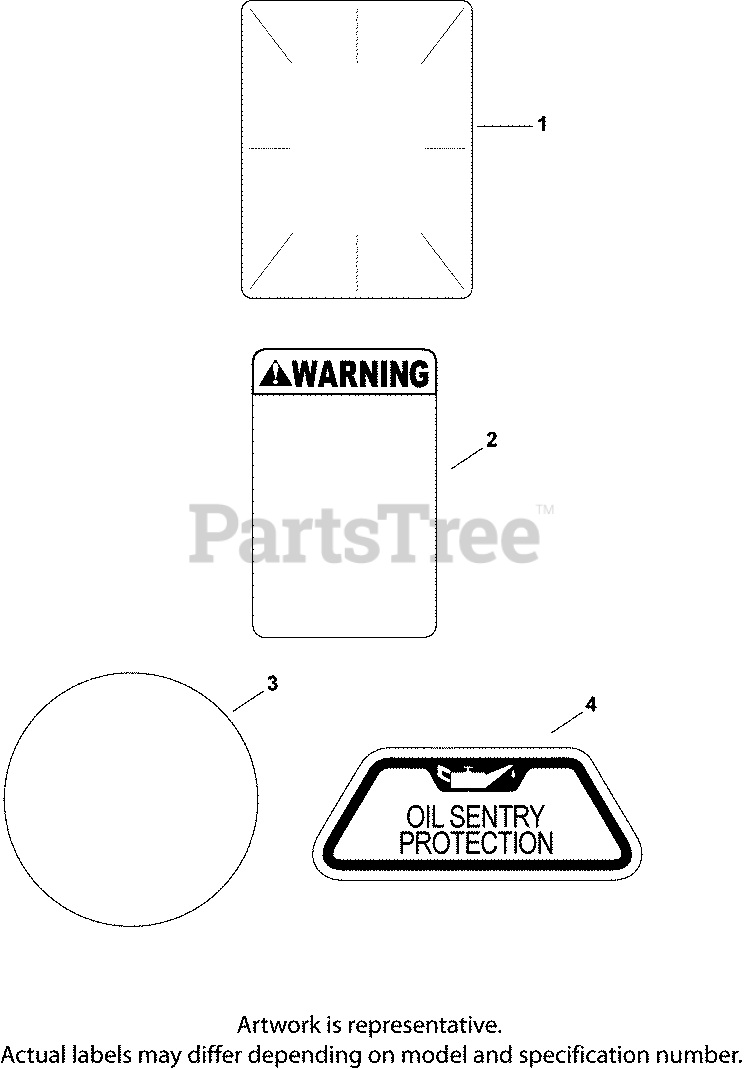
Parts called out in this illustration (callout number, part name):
1	DECAL, CLEAR LAMINATE USE 25 113 70-S
2	DECAL, CO WARNING
3	DECAL, GRASS SCREEN USE 24 113 499-S
4	DECAL, OIL SENTRY - (#DSC)
